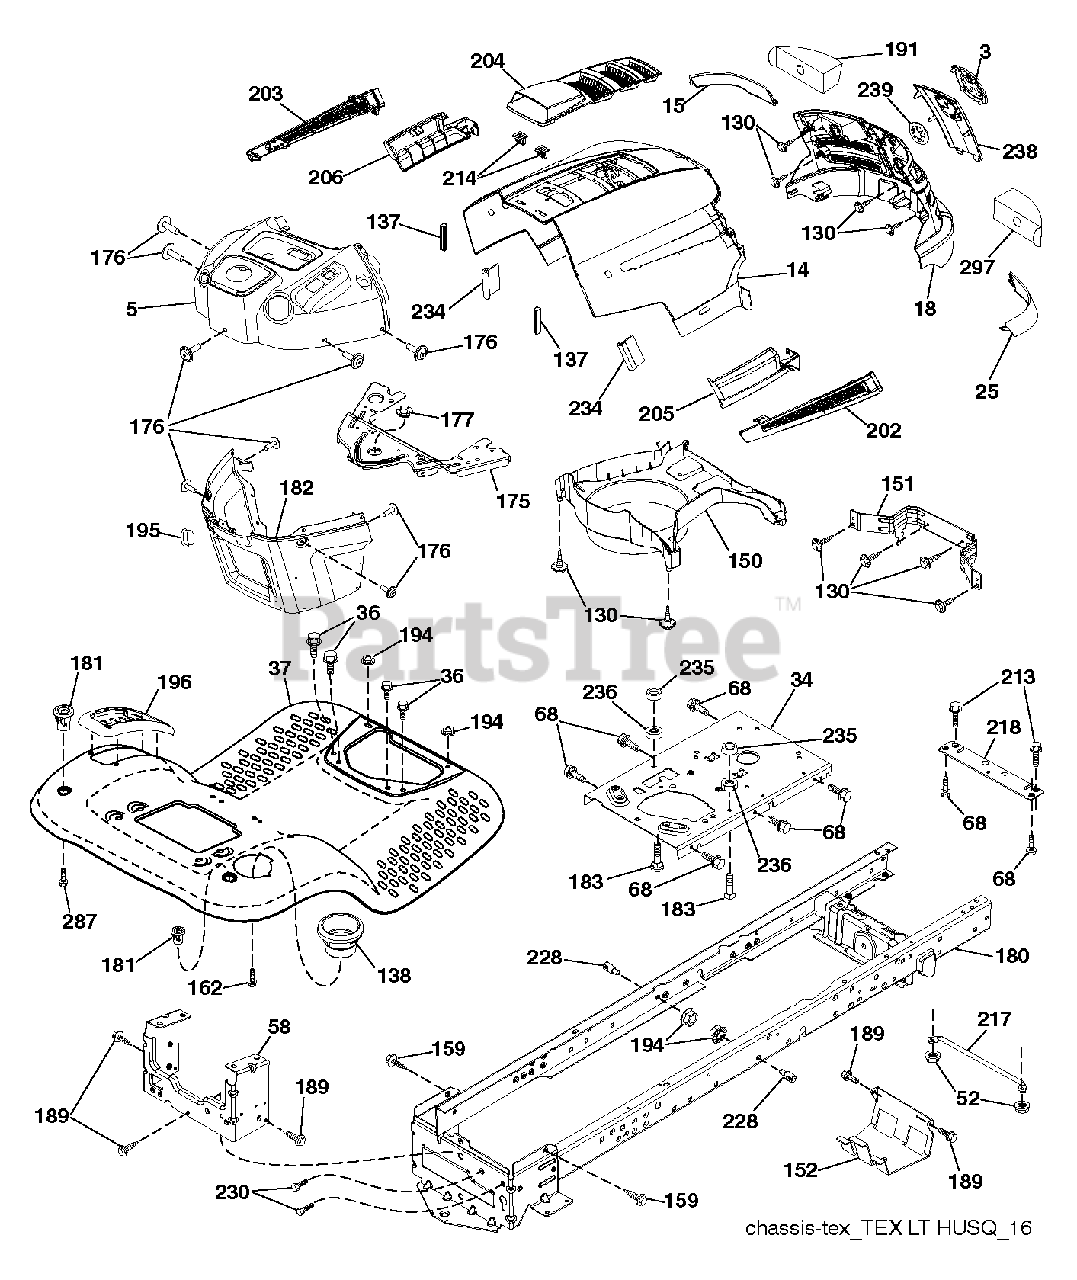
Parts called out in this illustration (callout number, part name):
3	RP LOGO
5	DASH
14	HOOD
15	LENS RH
18	RP GRILLE/LENS ASM.
25	LENS LH
34	PLATE.ENGINE.WELDED.CHASSIS
36	SCREW 5/16"
37	RP FENDER.TLT.FS.W/CPH.422
52	LOCKNUT
58	DRAWBAR UPPER 2PC SMALL FENDER
68	SCREW LT
130	SCREW.#10 X 0.750.BOS
137	BUMPER DASH
138	CUPHOLDER.TL.TEX.418
151	BRACKET PIVOT
152	SHIELD.BROWNING.W/TEX
159	SCREW, 3/8-16X3/4
162	SCREW.HI-LO.CONSOLE
175	CROSSMEMBER
176	SCREW.#10-24X5/8.RN.QU
177	BUSHING STEERING
180	CHASS.WLDMNT.TL.12GA/2P.48/54
181	BUSHING.MNT.FEND.CRGO.
182	DASH.LOWER.PREDATOR LT
183	BOLT.5/16-18X1-1/4 FULL.THREAD
189	SCREW
191	INSERT REFLECTIVE
194	NUT LOCK HEX FLANGE 5/16-18
195	PLUG DASH
196	RP CONSOLE.ASM.DECKLFT.GR/RBT.
202	VENT SIDE HOOD RH
203	VENT SIDE HOOD LH
204	VENT TOP HOOD
205	SKIRT SIDE RH
206	SKIRT SIDE LH
213	BOLT
214	CLIP.RETAINER.TINNER.
217	ROD.PIVOT.HOOD
218	X-PIECE.HOOD.STOP.NON/
228	STUD.FASTNER.W/ANTI-ROTATE
230	SHOULDER BOLT 5/16-18TT
234	BUMPER.HOOD.TEX.HUSQVARNA
235	SPACER FENDER
236	NUT.CENTERLOCK.5/16-
238	TRIM
287	SCREW 1/4X20
297	INSERT.REFLECTIVE.RH.
